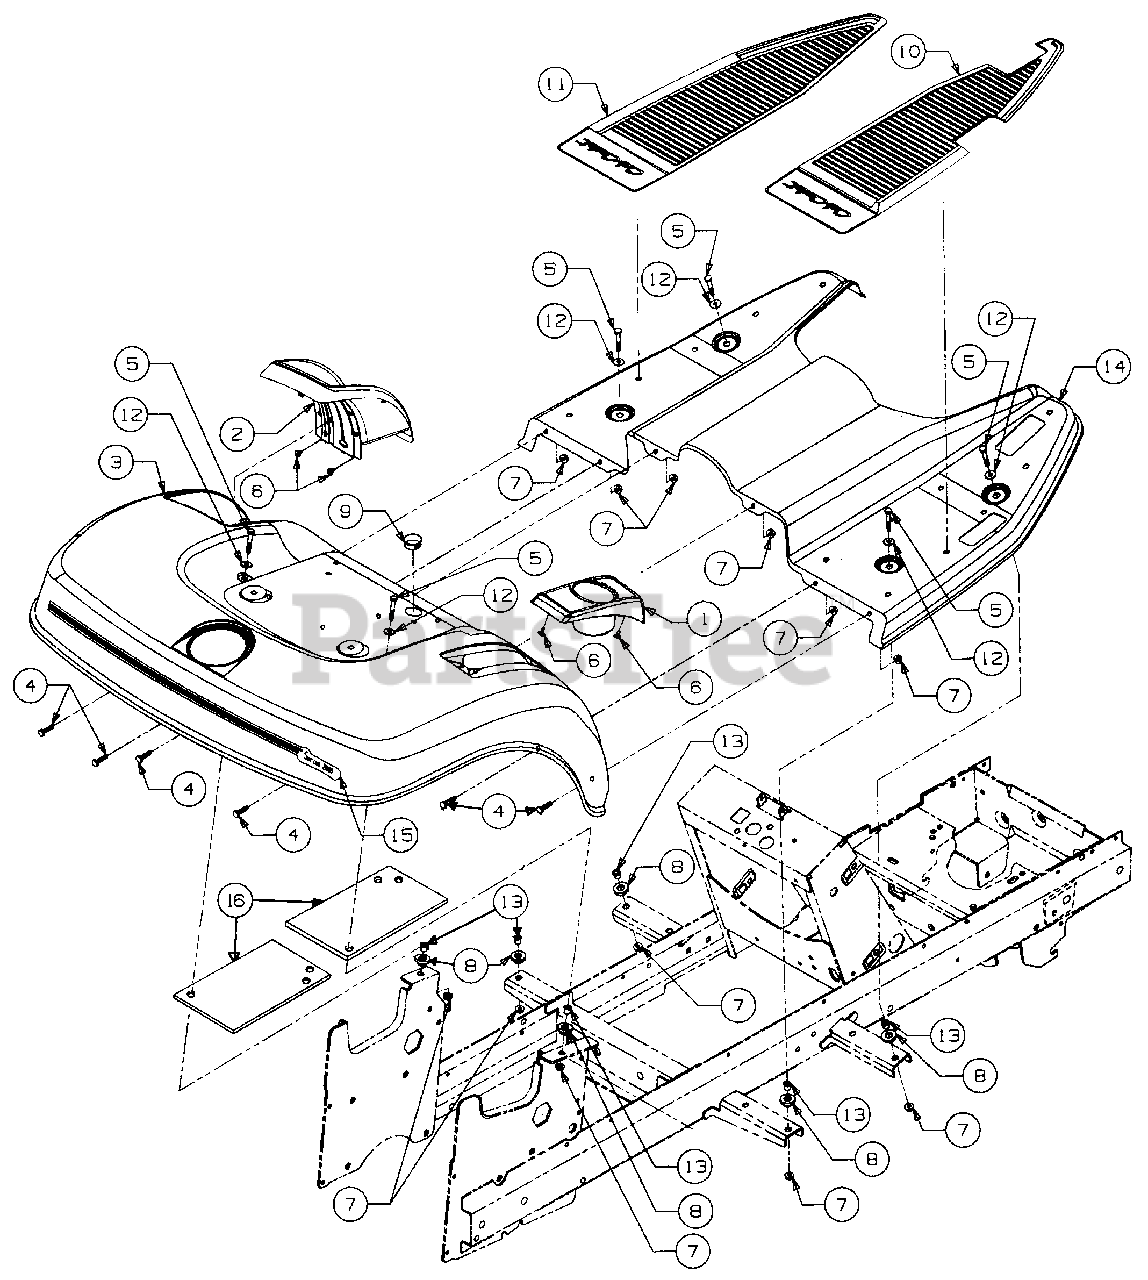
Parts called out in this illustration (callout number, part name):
1	Cup Holder
2	Cover, Implement Lift
4	Screw, Hex Cap, 1/4-20 x .62 GR5
5	Screw, Hex Cap, 1/4-20 x 1.0
6	Screw, Hex Tapp, #10 x .38 Lg
7	Nut, Hex Flange Lock, 1/4-20
8	Grommet, Insulater
9	Bushing, Snap, 7/8 ID
10	Pad, RH Foot
11	Pad, LH Foot
12	Washer, Flat, .255 x .72 x .06
13	Spacer, .28 ID x .40 OD x .42 Lg
14	Running Board w/Graphic
15	Graphic, Rear Fender
